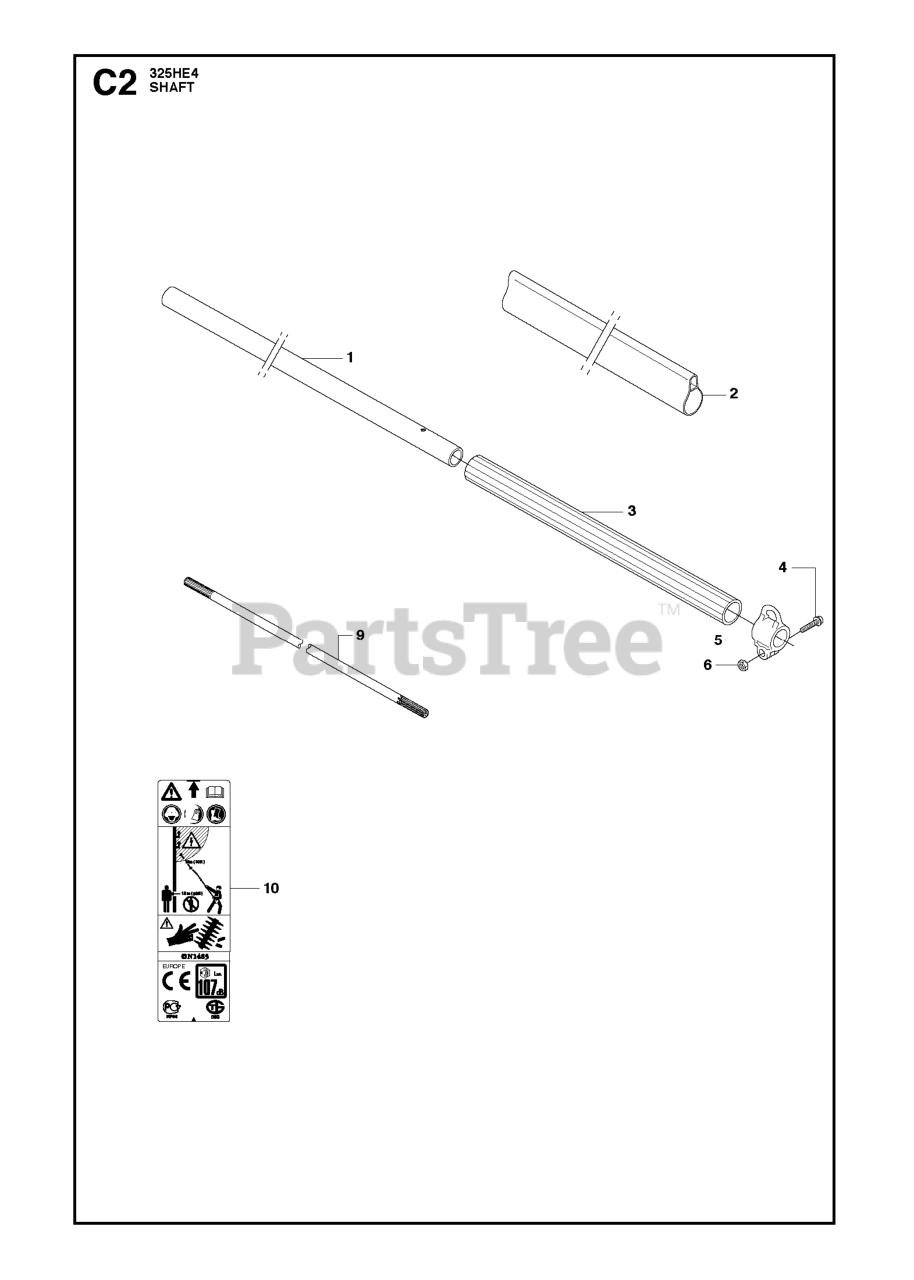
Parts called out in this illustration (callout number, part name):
5	HARNESS HOLDER
9	DRIVESHAFT
10	DECAL WARNING SPARK ARRESTOR
